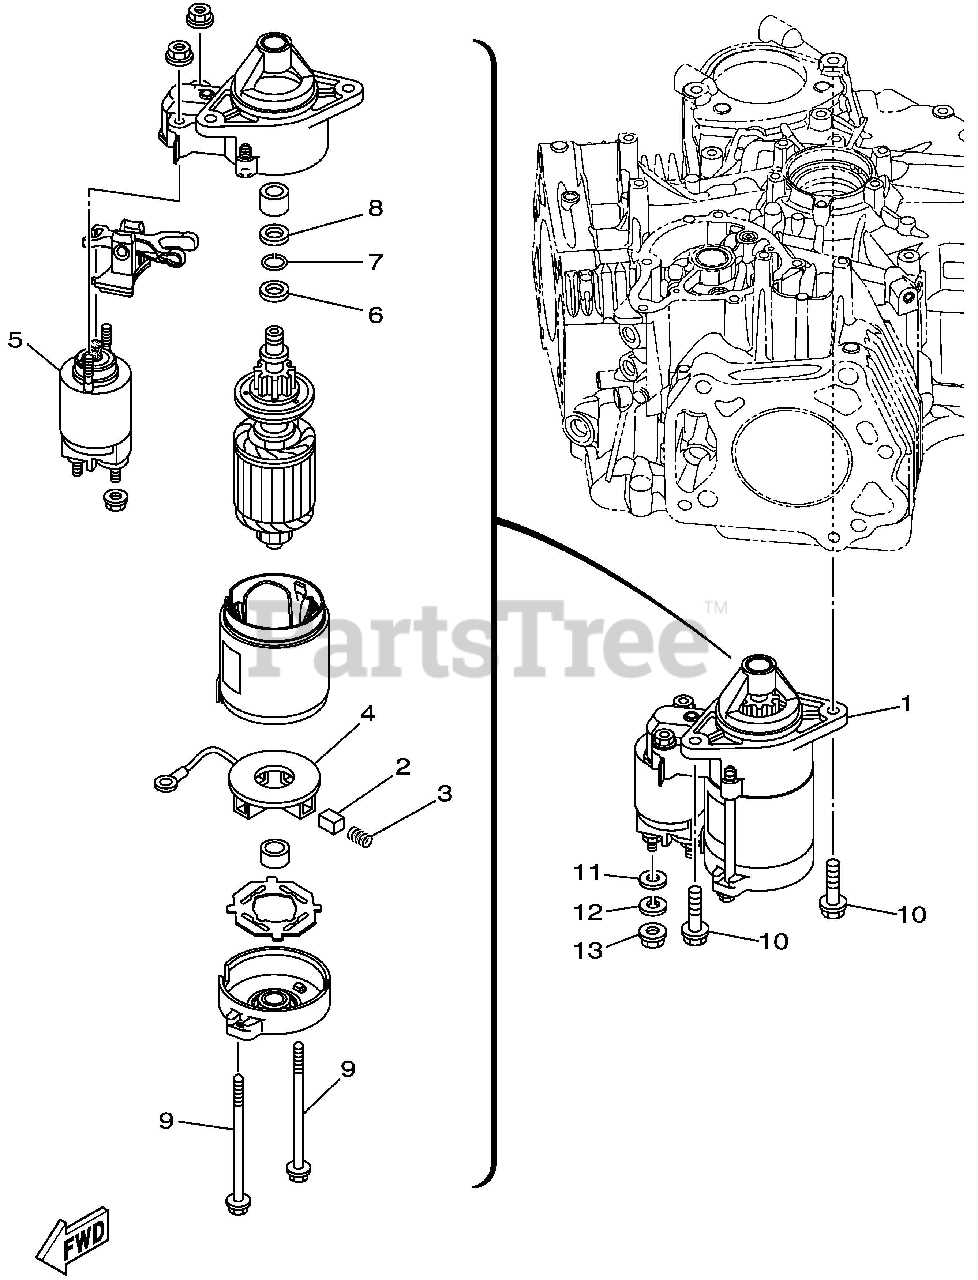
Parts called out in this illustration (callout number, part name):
1	STARTING MOTOR ASSY
3	SPRING, BRUSH
4	BRUSH HOLDER ASSY
5	STARTING SWITCH ASSY
6	RING, STOP
10	BOLT, FLANGE
11	WASHER, PLATE
12	WASHER, SPRING
13	NUT, HEXAGON
